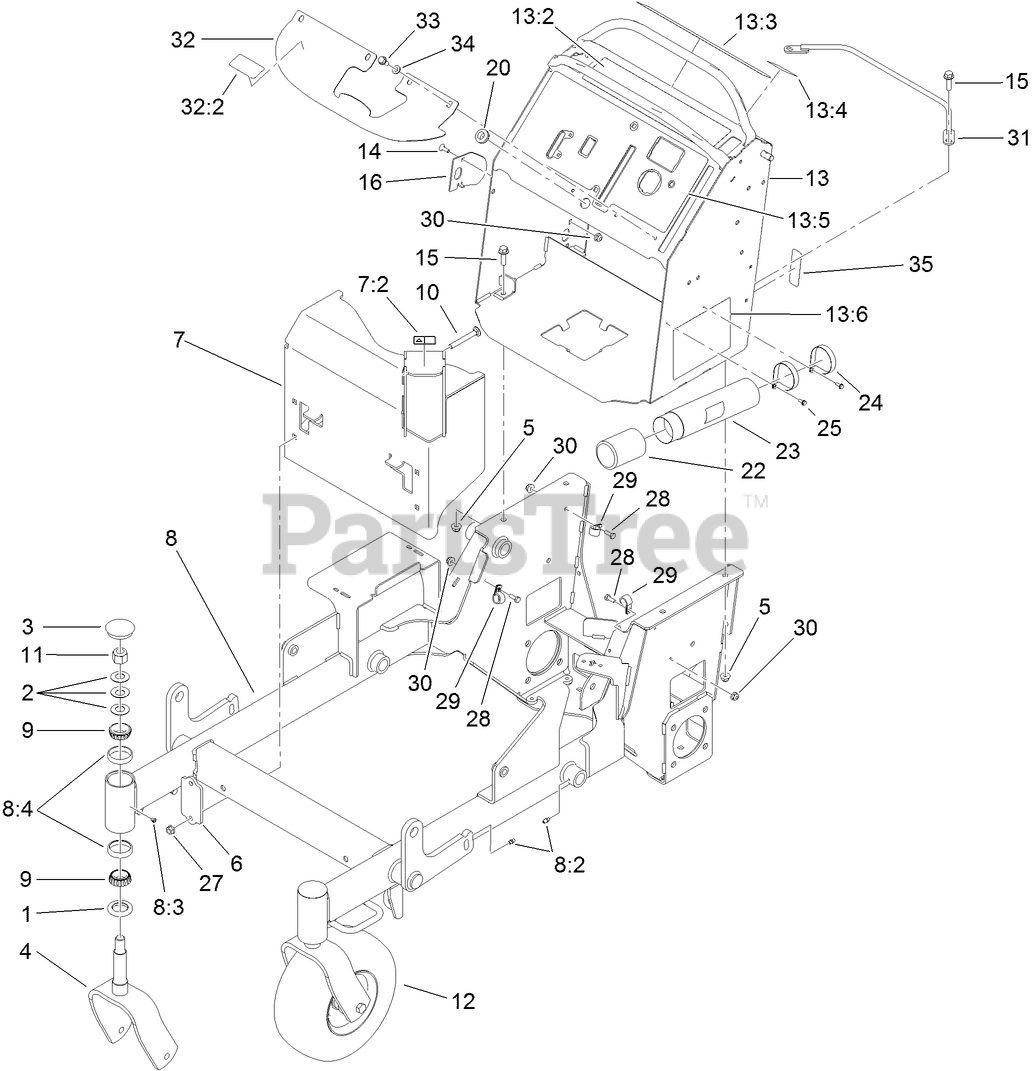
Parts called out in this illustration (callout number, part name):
1	SEAL-GREASE
2	WASHER-BELLVILLE
3	CAP-GREASE
4	FORK-CASTER
5	NUT-HF, NI
6	BRACKET-MOUNTING, GUARD
7	MUFFLER GUARD ASM
7:2	DECAL-WARNING
8	FRAME ASM
8:2	FITTING-GREASE
8:4	CUP-BEARING
9	BEARING-ROLLER, TAPERED
10	SCREW-CARR
11	NUT-LOCK, NI
12	WHEEL/TIRE AND BEARING ASM
13	CONTROL TOWER ASM
13:2	DECAL-OPC
13:3	DECAL-WARNING
13:4	DECAL-PANEL, CONTROL
13:5	DECAL-SERVICE AID
13:6	DECAL-STABILITY, CE
14	BOLT-CARR
15	SCREW-HHF
16	PLATE-STRIKER
20	GROMMET
22	CAP-HOUSING
23	TUBE-MANUAL
24	CLAMP-R
25	SCREW-TAPTITE
27	NUT-HF
28	SCREW-HH
29	CLAMP-CABLE
30	NUT-HF
31	RETAINER-CABLE
32	COVER-TANK
32:2	DECAL-FILL, FUEL
33	SCREW-HWHTF
34	WASHER-FLAT
35	DECAL-FUSE
